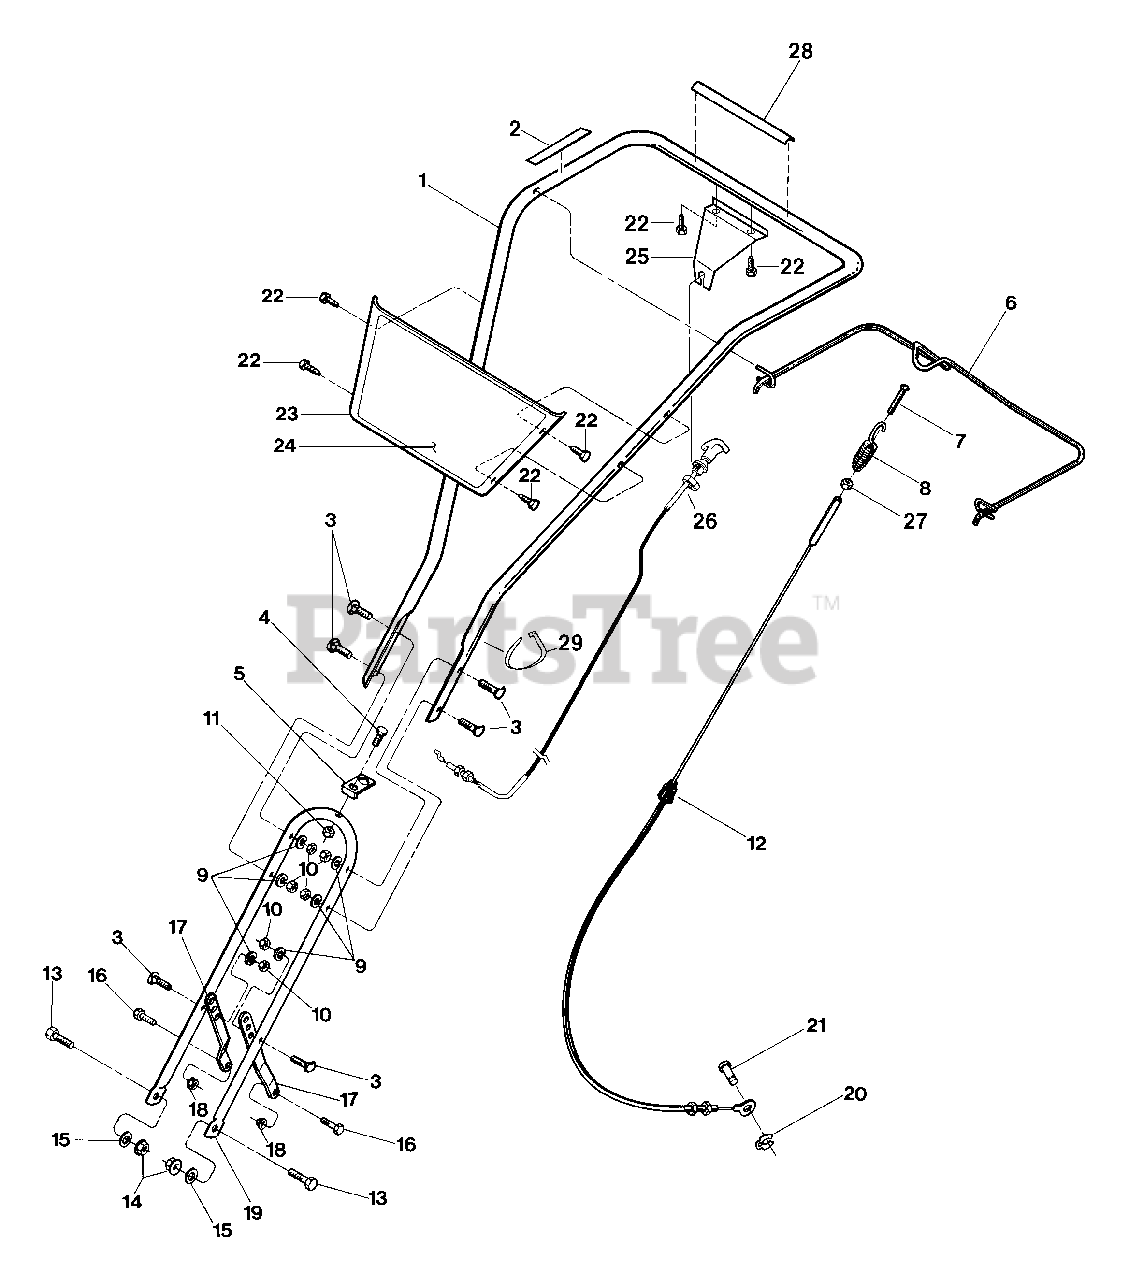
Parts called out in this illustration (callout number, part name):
1	Handlebar, Upper
2	Decal-Forward Clutch Bail
3	Hex Hd. Screw, 5/16-18 x 1-1/2
4	Hex Screw, 1/4-20 x 1-1/4
5	Bracket, Forward Clutch Cable
6	Bail, Forward Clutch
7	Screw, #10-24 x 2
8	Spring, Forward Clutch
9	Lockwasher, 5/16
10	Hex Nut, 5/16-18
11	Hex Locknut, 1/4-20
12	Cable Assembly, Forward Clutch
13	Hex Screw, 3/8-16 x 3/4
14	Hex Locknut, 3/8-16
15	Flat Washer, 3/8
16	Hex Screw, 5/16-18 x 3/4
17	Support, Handlebar
18	Hex Locknut, 5/16-18
19	Handlebar, Lower
20	Klip Ring
21	Clevis Pin
22	Hex Screw, 1/4-20 x 1/2, Self-Tapping
24	Decal-Model Name/Logo
25	Bracket, Reverse Clutch Cable
26	Cable Assembly, Reverse Clutch
27	Hex Nut, #10-24
28	Decal-Reverse Drive Control
29	Cable Tie
